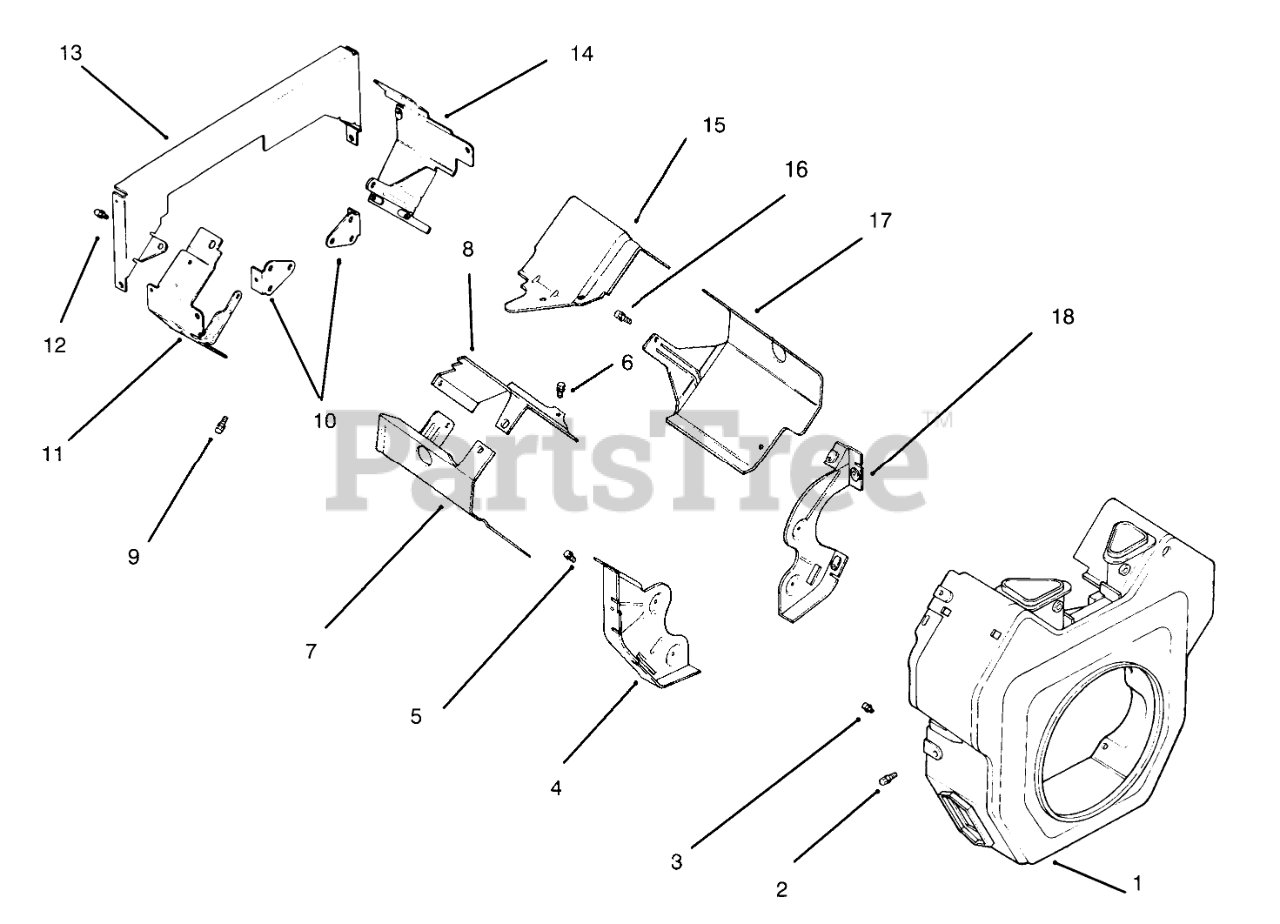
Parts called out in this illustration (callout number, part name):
1	Housing-Blower
3	Screw
4	Plate-Backing #2 side
5	Screw
6	Screw
7	Baffle-Cylinder Barrel #1 side
8	Baffle-Valley #1 side
9	Screw
10	Bracket-Support
11	Baffle-Ducted Air #1 side
13	Plat-Ducted Air Backing
14	Baffle-Ducted Air #1 side
15	Baffle, Valley #2 side
17	Baffle-Cylinder Barrel #2 side
18	Plate-Backing #1 side
